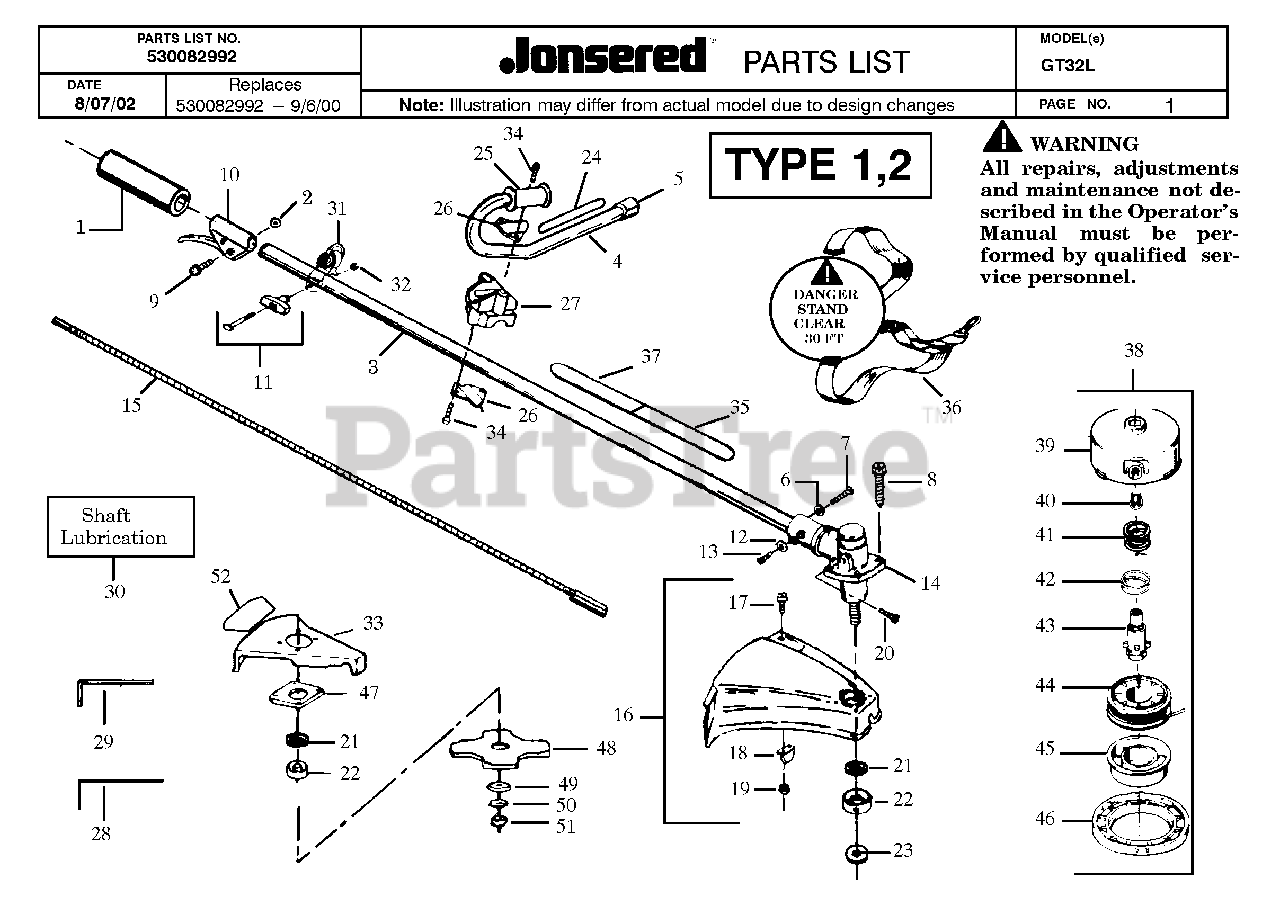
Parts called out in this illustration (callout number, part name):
1	DRIVE SHAFT GRIP
2	LOCKNUT-HEX 10-24
5	END CAP NLA
6	LOCKWASHER
7	SCREW-1/4-20X1 HEX SOC
9	SCREW-10-24 X 1" (UNC)
10	ASSY-THROTTLE HOUSING
11	KIT "T" HANDLE
12	LOCKWASHER-LOCATOR-TYPE 2
13	SCREW-10-24 X 7/16 (HEX
14	GEAR BOX ASSY/TYPE 1
16	KIT-SHIELD
18	LIMITER-LINE
19	NUT 10-24 NYLOC HEX
20	SCREW-5/16-24X3/8 HEX S
23	WASHER-GRASS
26	BRACKET-HANDLEBAR
27	CLAMP-HANDLEBAR
28	HEX WRENCH 5/32
29	HEX KEY 3/16"
31	ASSY-CLAMP HARNESS
36	STRAP-SHOULD.W/WARNING
38	TAP-N-GO I CCW
39	ASSY-HUB W/LN SAVER
40	SAVER-LINE
42	ADAPTOR SPRING
45	TAP BUTTON
47	PLATE-SHIELD RETENTION
49	WASHER-FLAT.
50	WASHER-SPRING BELLEVIL
51	NUT-FLANGE (LH)
530-016107	SCREW - SHIELD
